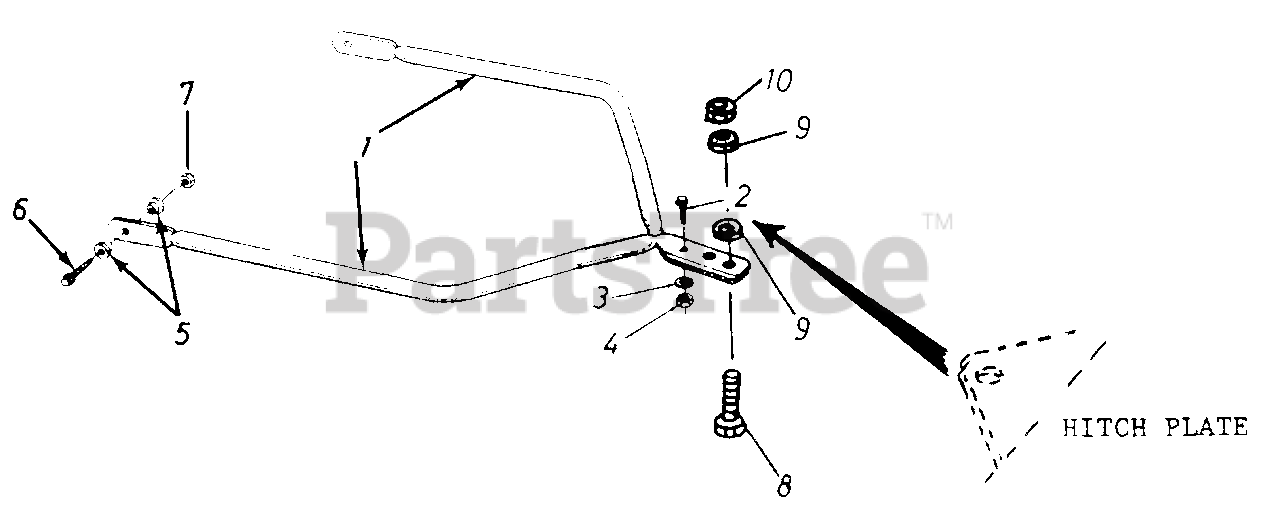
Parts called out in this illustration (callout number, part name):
3	L.-Wash. 1/4" I.D.*
4	Hex Nut 1/4-2 Thd.*
5	Shoulder Spacer
6	Hex Wash. Hd. Self-Tapp Scr. 5/16-18 x 1.0" Lg.*
7	Hex Nut 5/16-18 Thd.*
8	Shld. Bolt .496 Dia. I
9	Belle-Wash. .39 I.D. x 1.12 O.D.
10	Hex Jam L-Nut 3/8-16 Thd.
